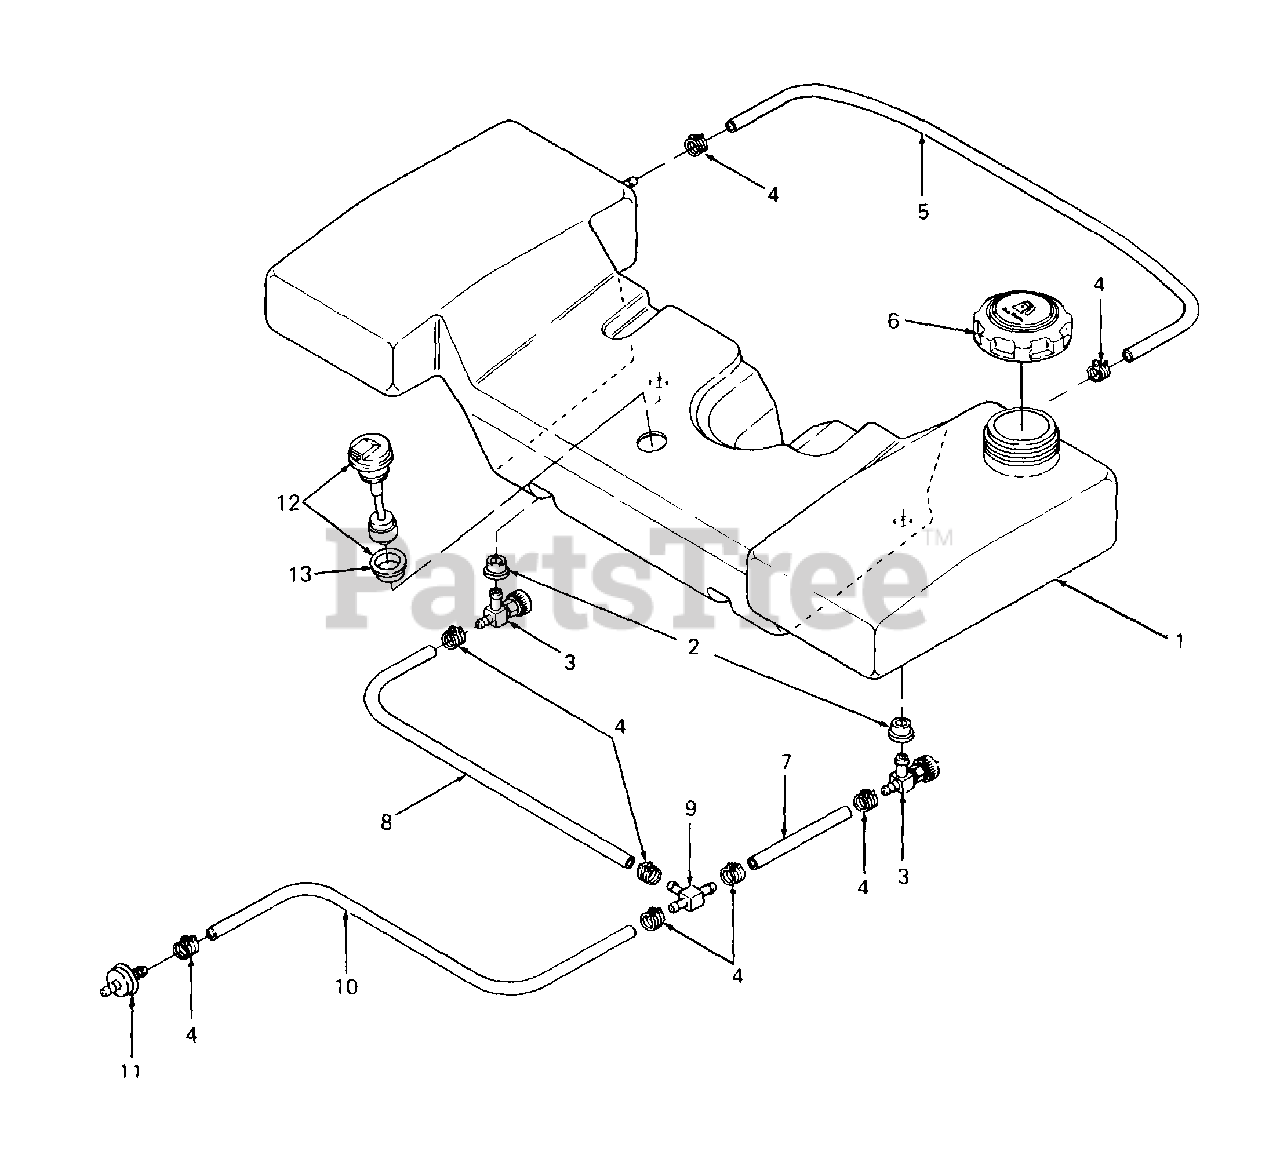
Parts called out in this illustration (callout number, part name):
1	Tank, Fuel
2	Bushing
3	Valve, Fuel Shutoff
4	Clamp, Hose
5	Line, Fuel -24" Lg
6	Cap, Fuel
7	Line, Fuel -5" Lg
8	Line, Fuel -17" Lg
9	T-Fitting
10	Line, Fuel -41" Lg
11	Filter, Fuel
12	Sensor, Low Fuel
13	Bushing, Rubber
